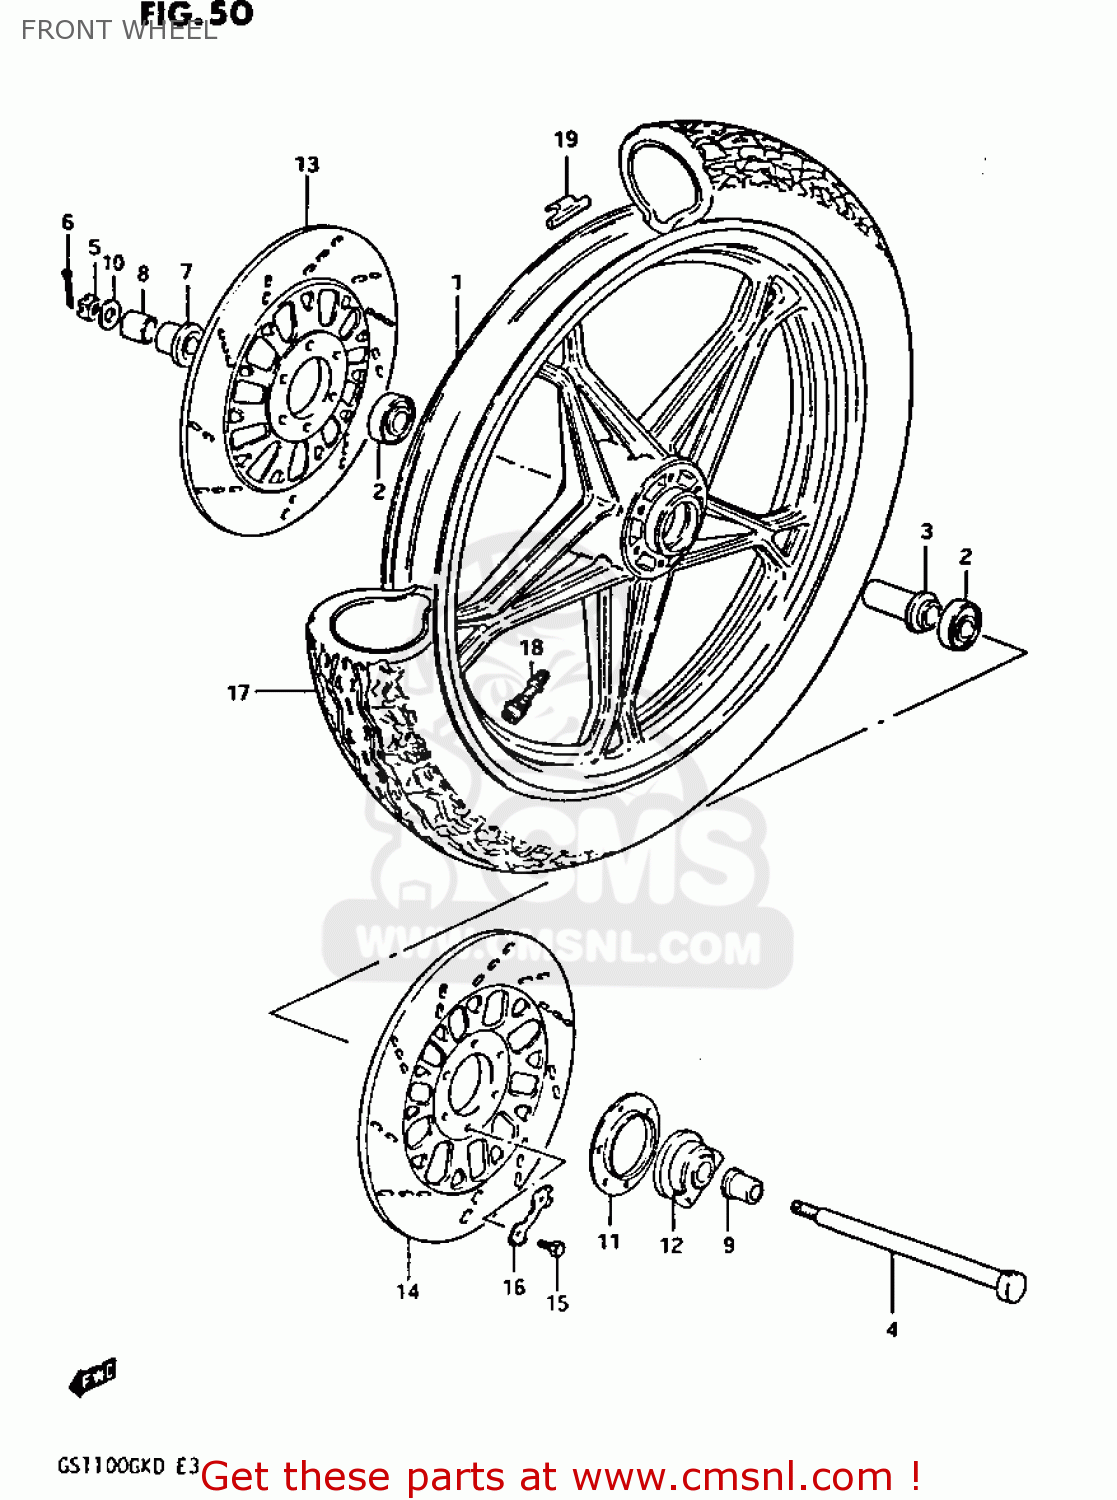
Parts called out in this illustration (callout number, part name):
1	CASTING WHEEL,FRONT 2.15
2	BEARING
3	SPACER,FR HUB BEARING
4	AXLE,FRONT
5	NUT 12MM
6	COTTER PIN
7	SPACER,FR AXLE,R
8	SPACER
9	SPACER,FRONT AXLE
10	WASHER
11	DUST SEAL,SPEEDOMETER GEAR BOX
12	BOX ASSY,SPEEDOMETER GEAR
13	DISC,FR BRAKE,R
14	DISC,FR BRAKE,L
15	BOLT(8X25)
16	WASHER
17	TIRE,FRONT
18	VALVE ASSEMBLY,WHEEL RIM,J
19	BALANCER,WHEEL
